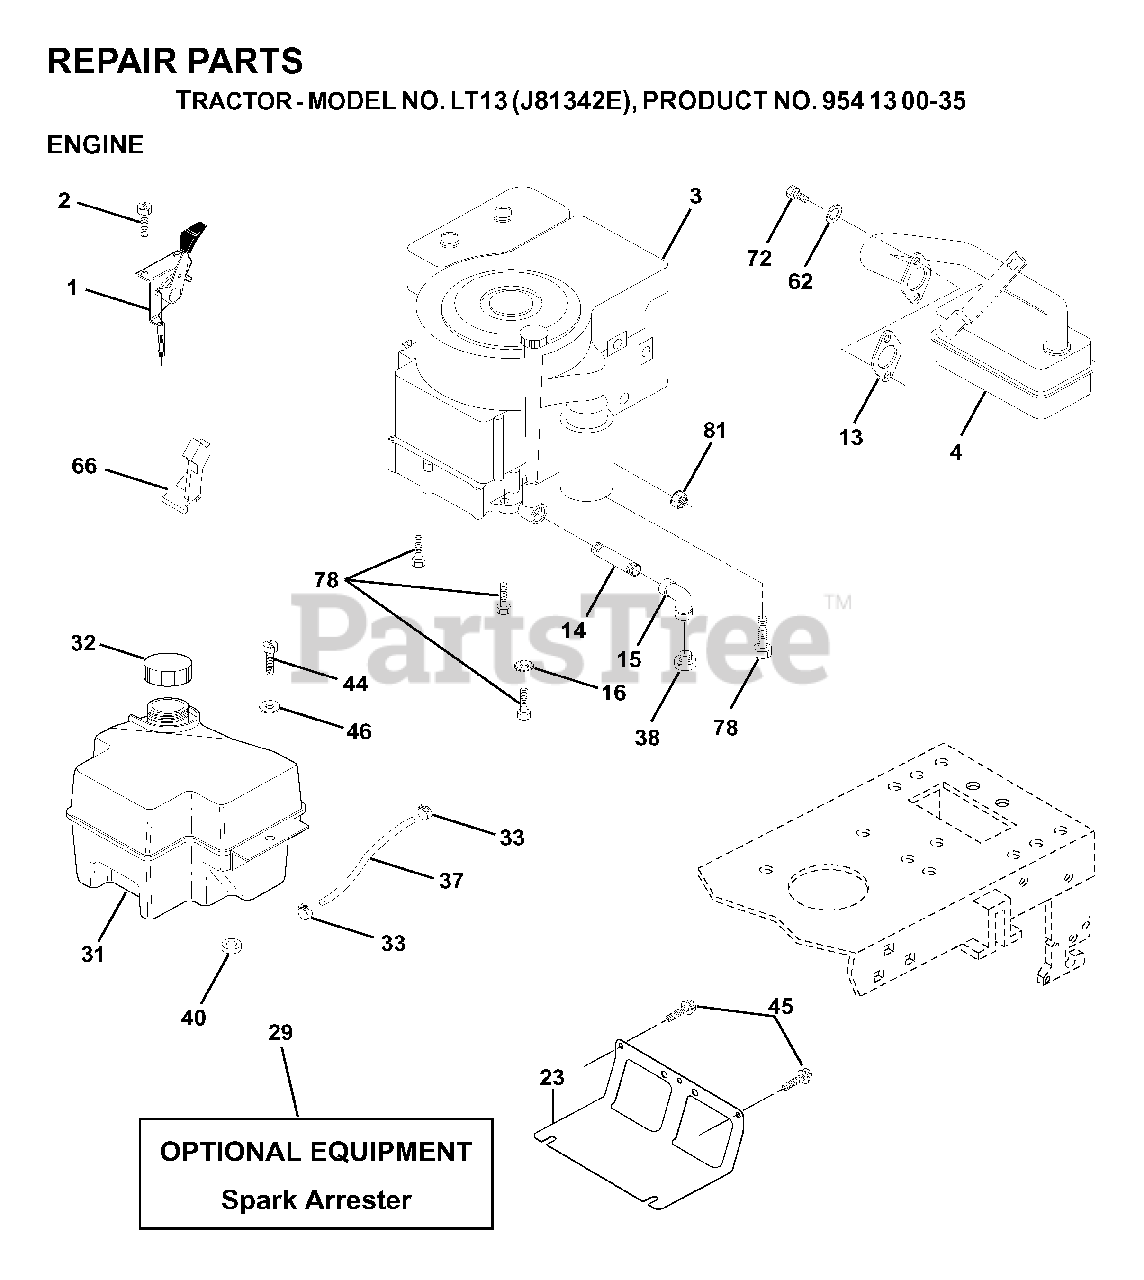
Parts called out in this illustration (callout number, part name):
1	CONTROL
2	SCREW LT
13	REPL BY 532 27 22-93
15	ELBOW
16	LOCKWASHER
23	SHEILD.BROWNING.DBR.GUARD
29	ARRESTER SPARK (OPTIONAL)
31	FUEL TANK
32	FUEL CAP
33	HOSE CLAMP
37	LINE.FUEL.20
40	GROMMET T
44	SCREW HEX CRT
45	SCREW 3/8-16X3/4
62	LOCKWASHER
66	STOP THROTTLE
78	SCREW.3/8-16
81	NUT FLANGE 1/4-20 STARTER NUT
